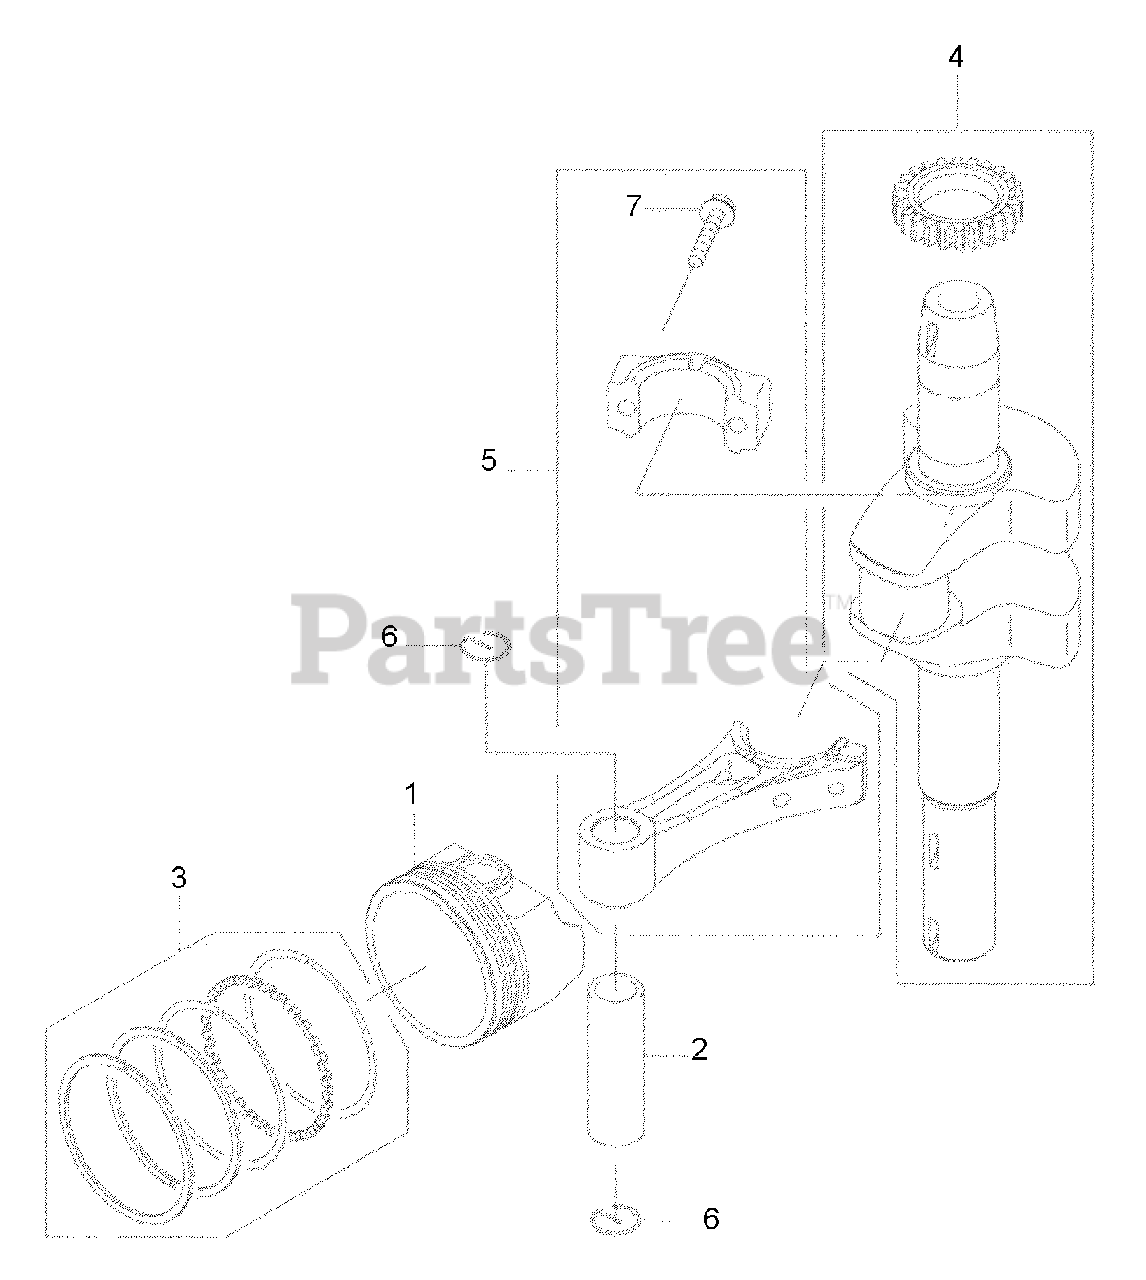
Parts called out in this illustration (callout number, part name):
1	Piston
3	Piston Ring Set
4	Crankshaft With Gear
5	Connecting Rod Assy.
